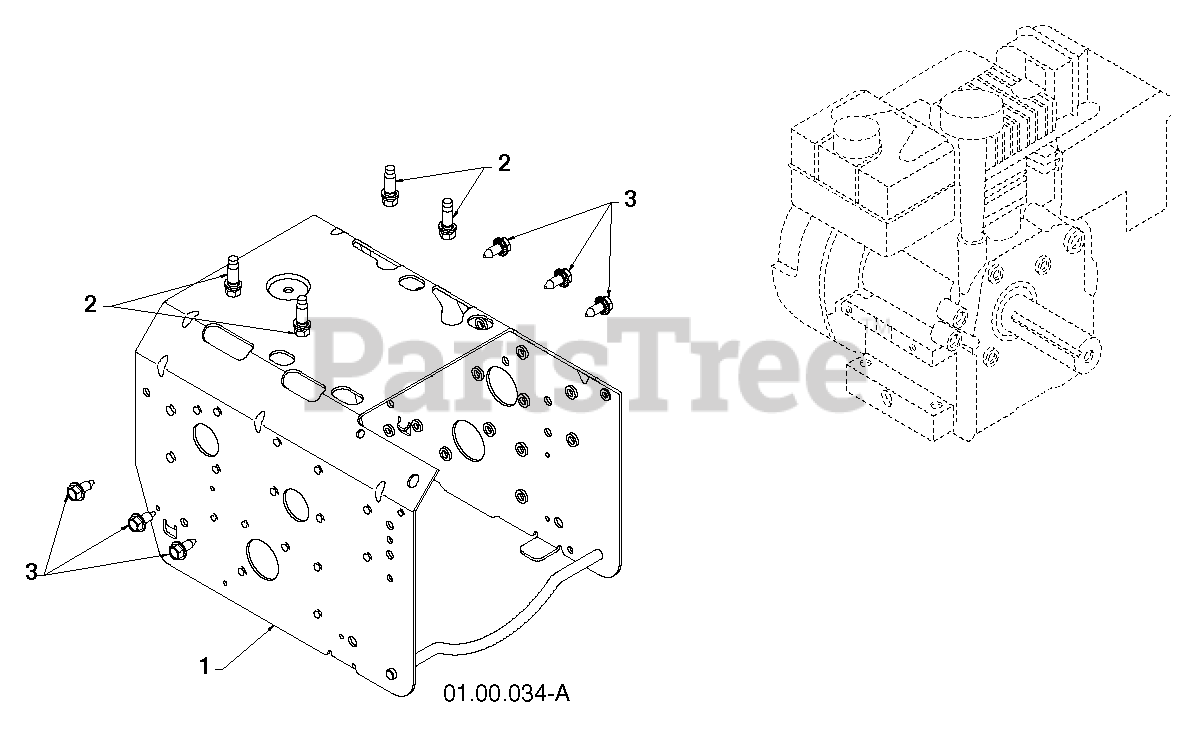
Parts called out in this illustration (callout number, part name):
1	FRAME.WELD.CHAIN.PNT.YELLOW
2	BOLT 3/8-16X1-1/8
3	BOLT.HEX.HD.WASHER.5/16-18X.75
